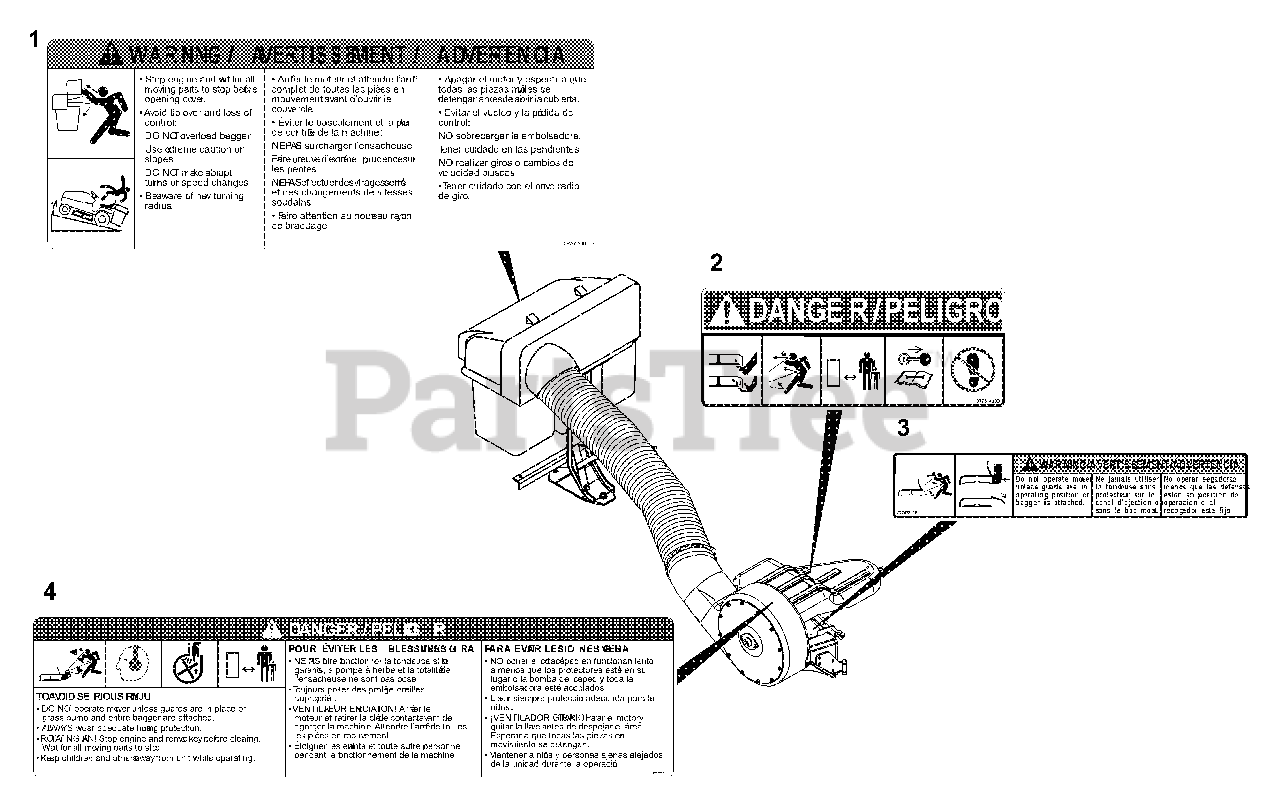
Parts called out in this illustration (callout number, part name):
1	DECAL-WARNING,BAGGER COVER
2	DECAL, MOWER PAN DANGER
3	DECAL, WARNING
4	DECAL-CAUTION, GRASS PUMP
